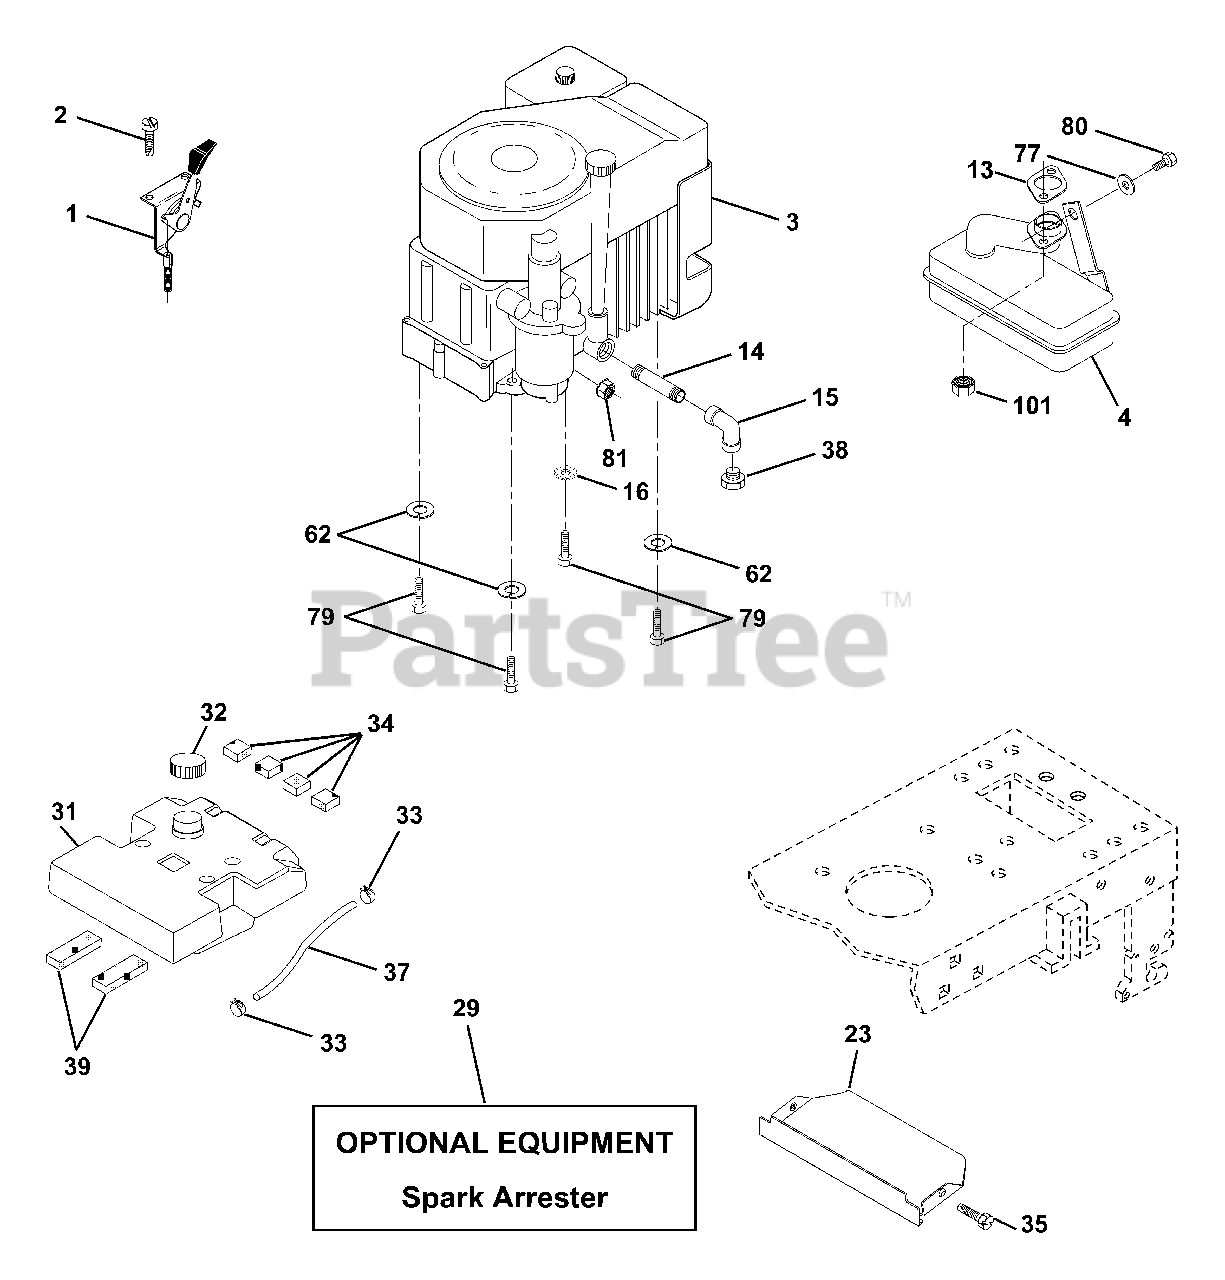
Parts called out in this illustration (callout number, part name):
1	Control Th/ch 27. LH. Flag Dom.
2	Screw Hex Thd Cut 1/4-20x5/8 T
4	Muffler LT Kohler 12.5/15HP
14	Nipple Pipe 3/8 Npt X 3-1/2
15	Elbow Std 90 Degree 3/8-18 Npt
16	Washer Lock Ext Tooth 5/16
23	Shield Browning/Debris Guard
29	Kit Spark Arrestor (Flat Scrn)
31	Tank Fuel 3.5 STLT W/O Sensor
32	Cap Asm Fuel W/sym Vented
33	Clamp Hose Black
34	Pad Spacer
35	Screw
37	Line Fuel 7.5"
38	Plug Oil Drain
39	Pad Idler 1.75 x .75 x .06
40	Bushing
41	Stem Tank Fuel
62	Washer Lock Hvy Hlcl Spr 5/16
77	Washer 5/16 x 3/4 x 16 Ga.
79	Bolt Hex
80	Bolt Hex Hd. 5/16-18unc x 1/2
81	Nut Flange 1/4-20 Starter Nut
